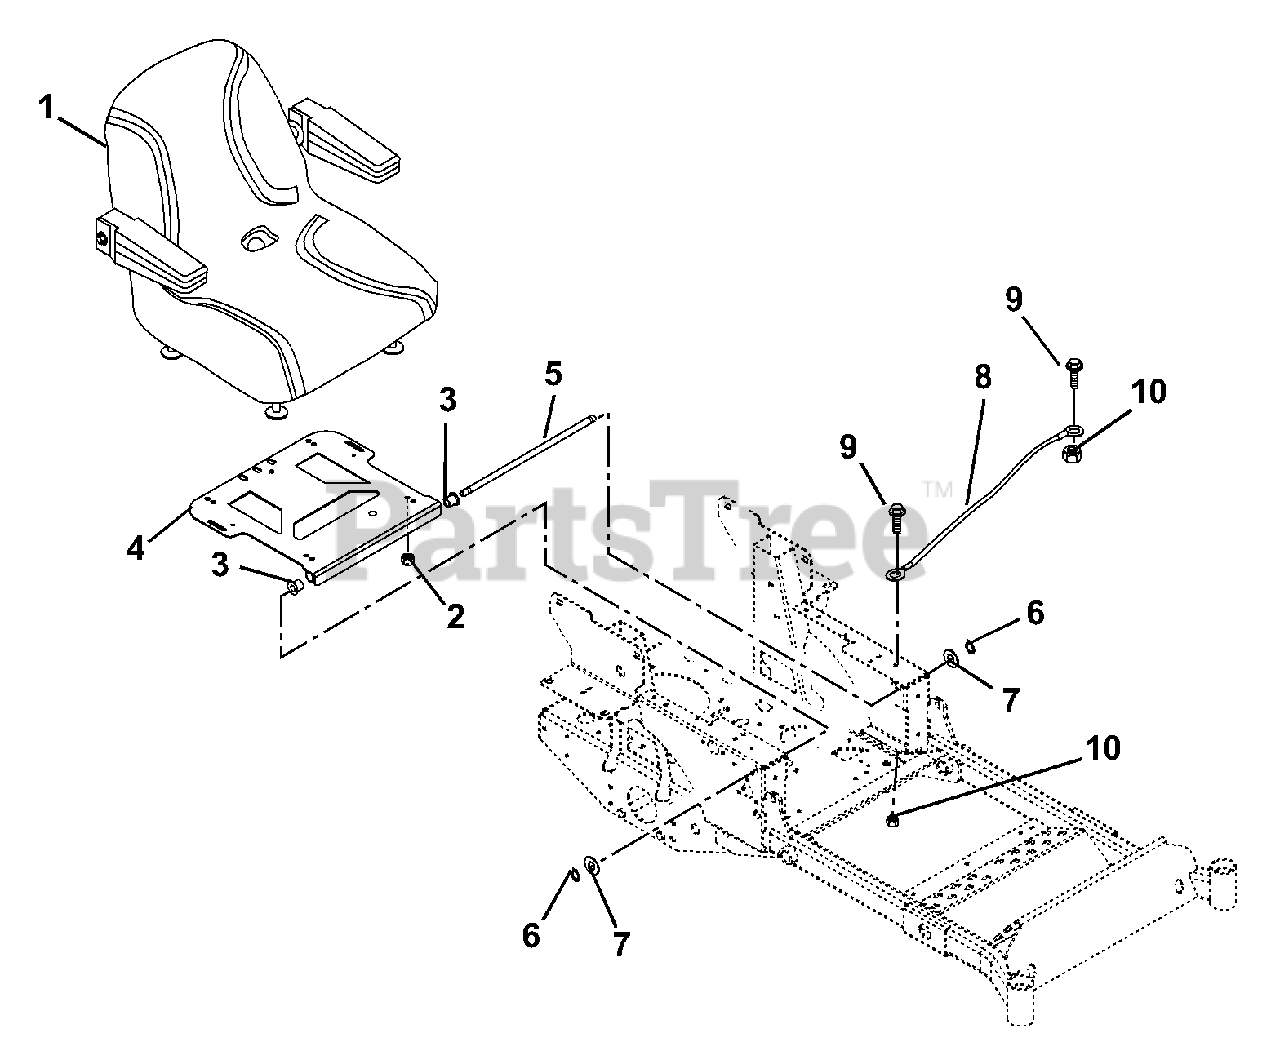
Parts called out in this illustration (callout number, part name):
1	ASSM, SEAT W/REPLA ARMRESTS
2	@NUT-LK-NYL-FLG .31-18 YWZC
3	BSHG-FLG .515X.750X.745X1.00NY
4	WMT, SEAT PIVOT MOUNT
5	ROD, SEAT FRAME PIVOT
6	RG-RTNG-EXT .500X.050 (SNAP)
7	@WSHR-FL-STL.531X1.06X.095YWZC
8	CBL,HOOD
9	@BLT-HEX .25-20X.75 GR5 YWZC
10	@NUT-LK-NYL-FLG .25-20 YWZC
11	KNOB - WING .312-18 UNC
